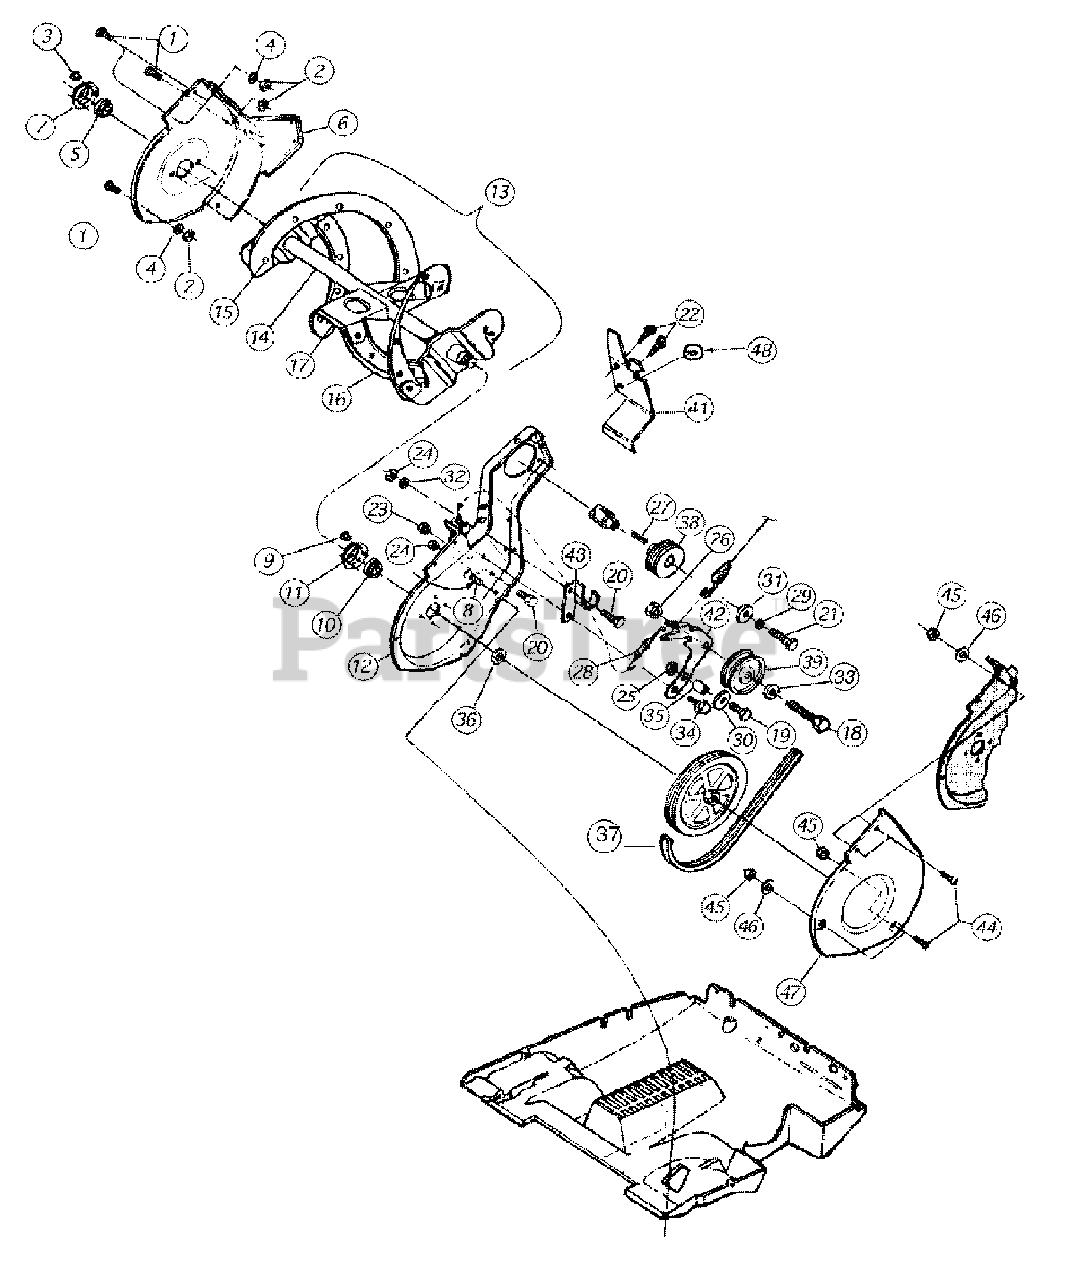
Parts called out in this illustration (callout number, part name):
1	Scr: #10-24:.625 Pan Trx
2	Hex Nut
3	Rivet
4	Flat Washer
5	Ball Bearing, Auger Axle
8	Hex Screw: 1/4 - 20 X .625 Gr 2
9	Rivet .252 Dia X .31
10	Ball Bearing, Auger Axle
11	Retainer Bearing
14	Auger Assembly, Weld.
15	Rivet, Truss
16	Auger Blade
17	Auger Paddle
18	Hex Screw: 3/8 - 16 X 1.50 Gr 5
19	Hex Screw: 1/4 - 20 X 1.0 Gr 5
20	Scr:AB: 1/4-14: .625:Hxindwsh
21	Hex Screw: 5/16 - 24 X .88 Gr 2
22	Hex Screw
23	Nylock
24	Top Lock Nylon Insert
25	Lock Nut: 1/4 - 20
26	Flanged Lock Nut
28	Extension Spring
29	Lock Washer
30	Flat Washer: .344 ID X 1.12 OD
31	Flat Washer: .385 ID X .87 OD X .092
32	Flat Washer: .25 ID X .62 OD
33	Flat Washer: .406 ID X .81 OD X .051
34	Shoulder Screw
35	Spacer, Brake Belt
36	Spacer, Auger Pulley
37	Belt, Auger Drive
38	Engine Pulley
39	Idler Pulley
41	Shield, Bolt
42	Idler Arm
43	Bracket, Belt
44	Machine Screw #10 - 24 X .62
45	Hex Nut
46	Flat Washer: .218 ID X .62 OD X .063
47	Belt Guard
48	Auger Pulley
